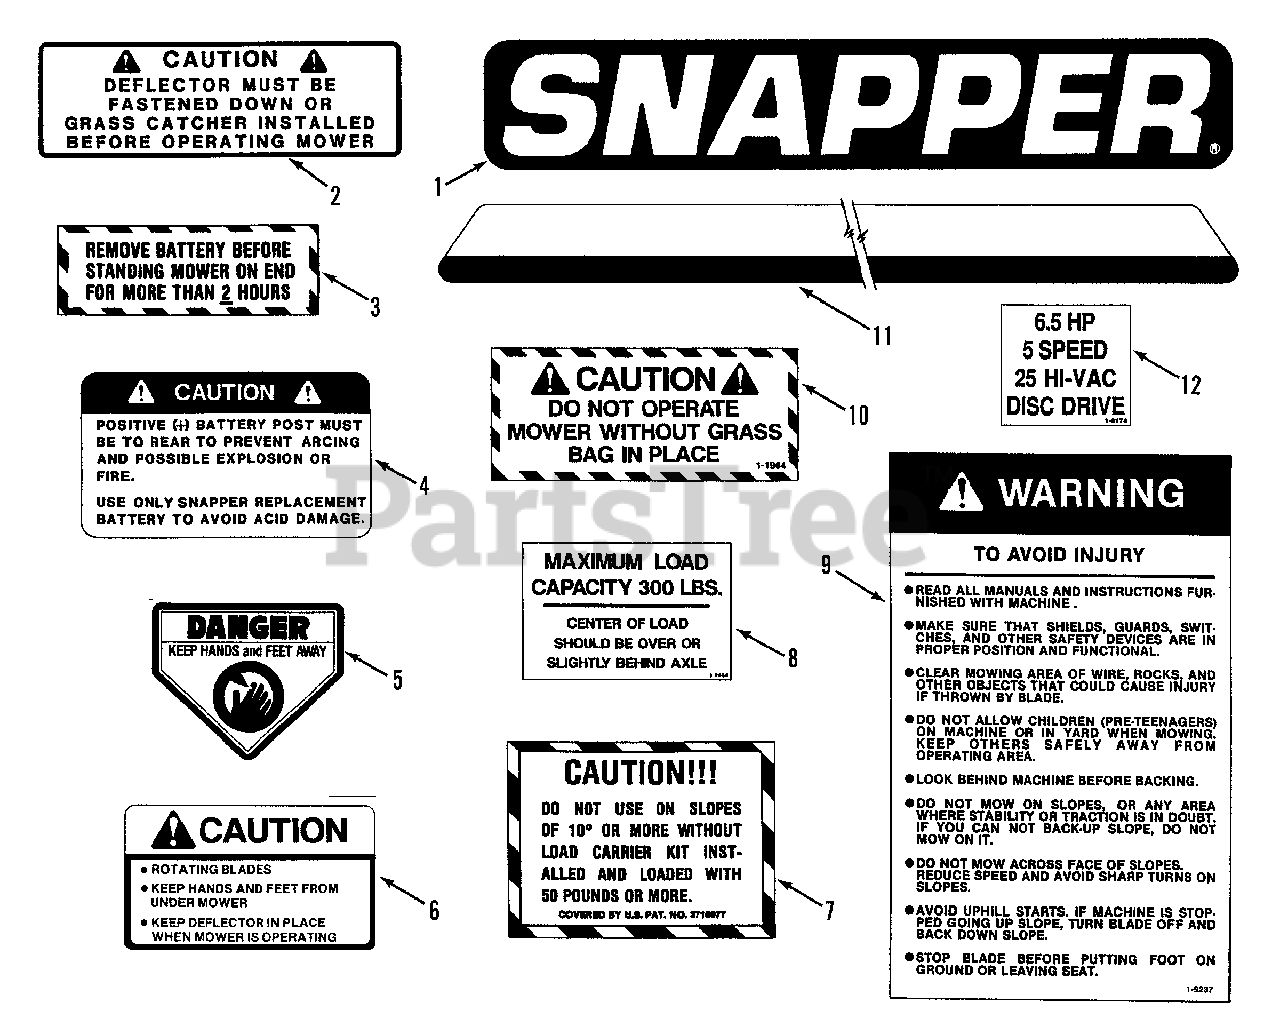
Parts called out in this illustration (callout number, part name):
1	DECAL, Snapper
2	DECAL, Caution, Deflector
3	DECAL, Battery
4	DECAL, Caution, Battery
5	DECAL, Danger
6	DECAL, Caution - Rotating Blades
7	DECAL, Caution, Carrier
8	DECAL, Maximum Capacity
9	DECAL, Warning, Instruction
10	DECAL, Caution, Grass Bag
11	DECAL, Pin Stripe
12	DECAL, Model, 6.5 HP, 25" Cut
